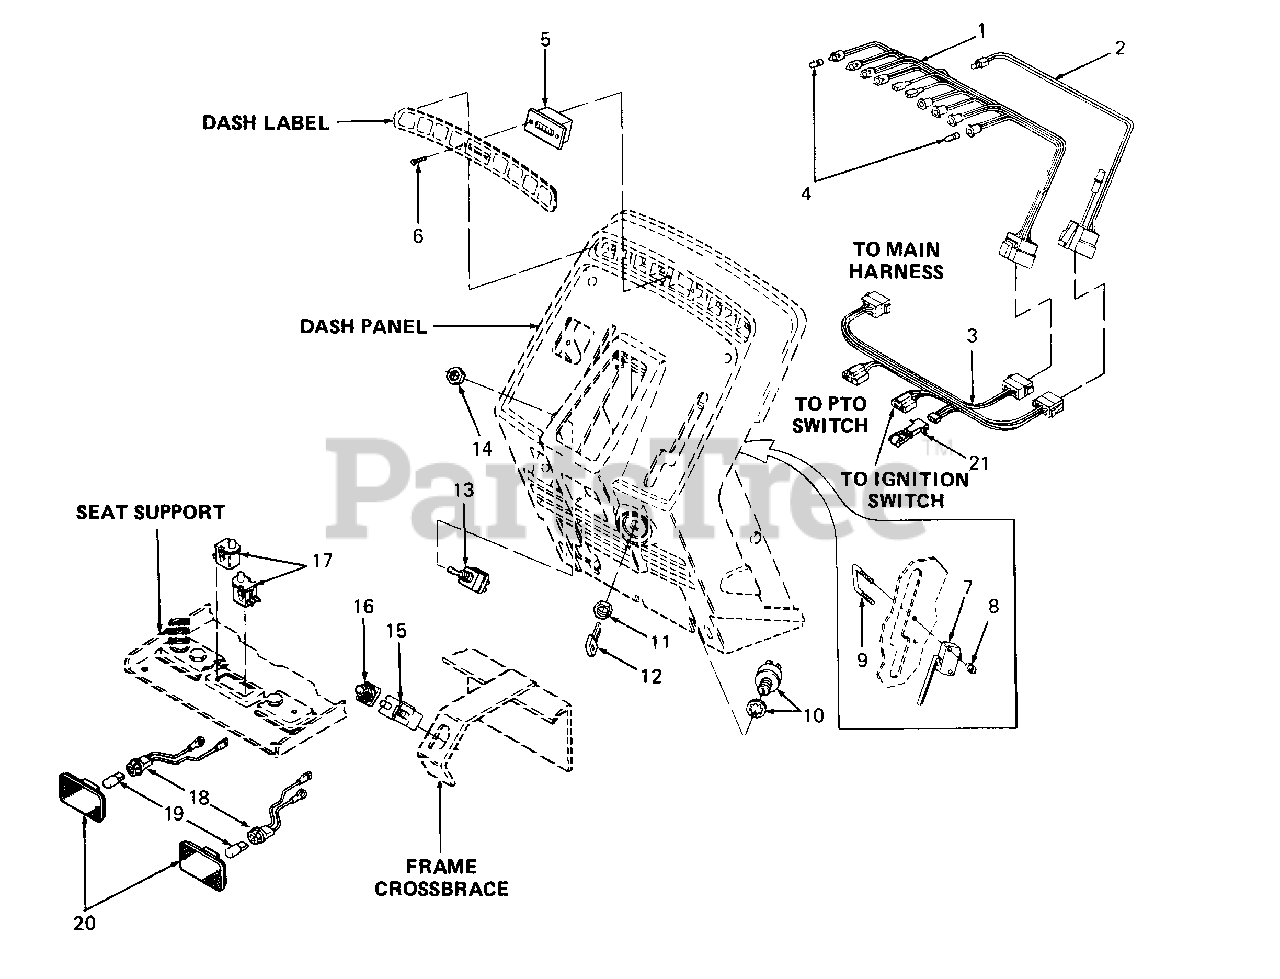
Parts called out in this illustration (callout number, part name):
1	Harness, Indicator Wire
2	Harness, Indicator Adapter
3	Harness, Pedestal
4	Bulb, Indicator
5	Hour Meter
6	Screw, Truss Hd Tapp, #6 X .62 Lg
7	Switch, Reverse
8	Nut, Hex Insert Lock, #4-40
9	Screw, Switch
10	Switch, Ignition
11	Nut, Ignition Switch
12	Key, Ignition (Set of 2)
13	Switch, PTO
14	Nut, Hex, 1/2-27 X .100 Thk
15	Switch, Interlock
16	Boot, Switch
17	Switch, Snap Mount - Normally Open (Black)
18	Cable Assy, Tail Light
19	Bulb, Tail Light
20	Lens Assy, Tail Light
21	Diode Assy
